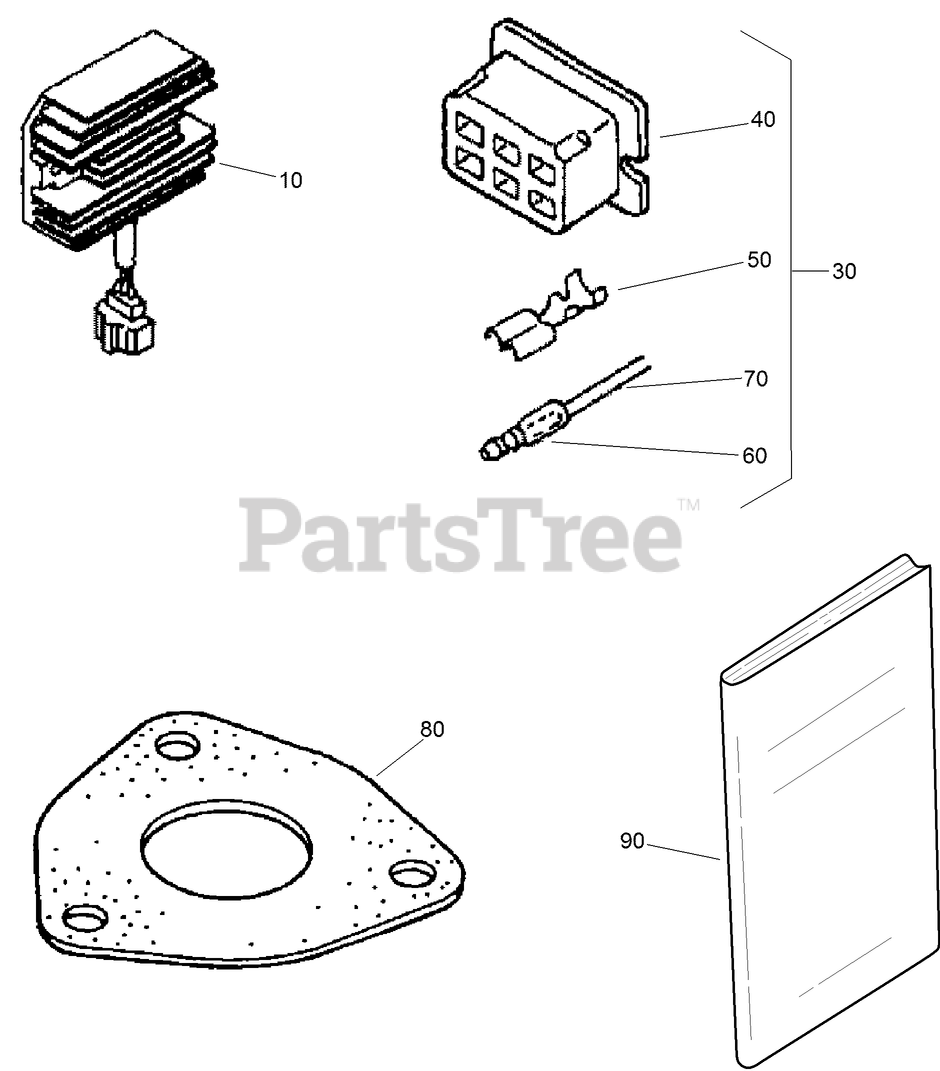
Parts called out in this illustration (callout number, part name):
10	REGULATOR ASM
30	COUPLER ASM
40	CONNECTOR
50	TERMINAL
60	TERMINAL
70	SLEEVE
80	GASKET-MUFFLER
90	MANUAL-OPERATOR
